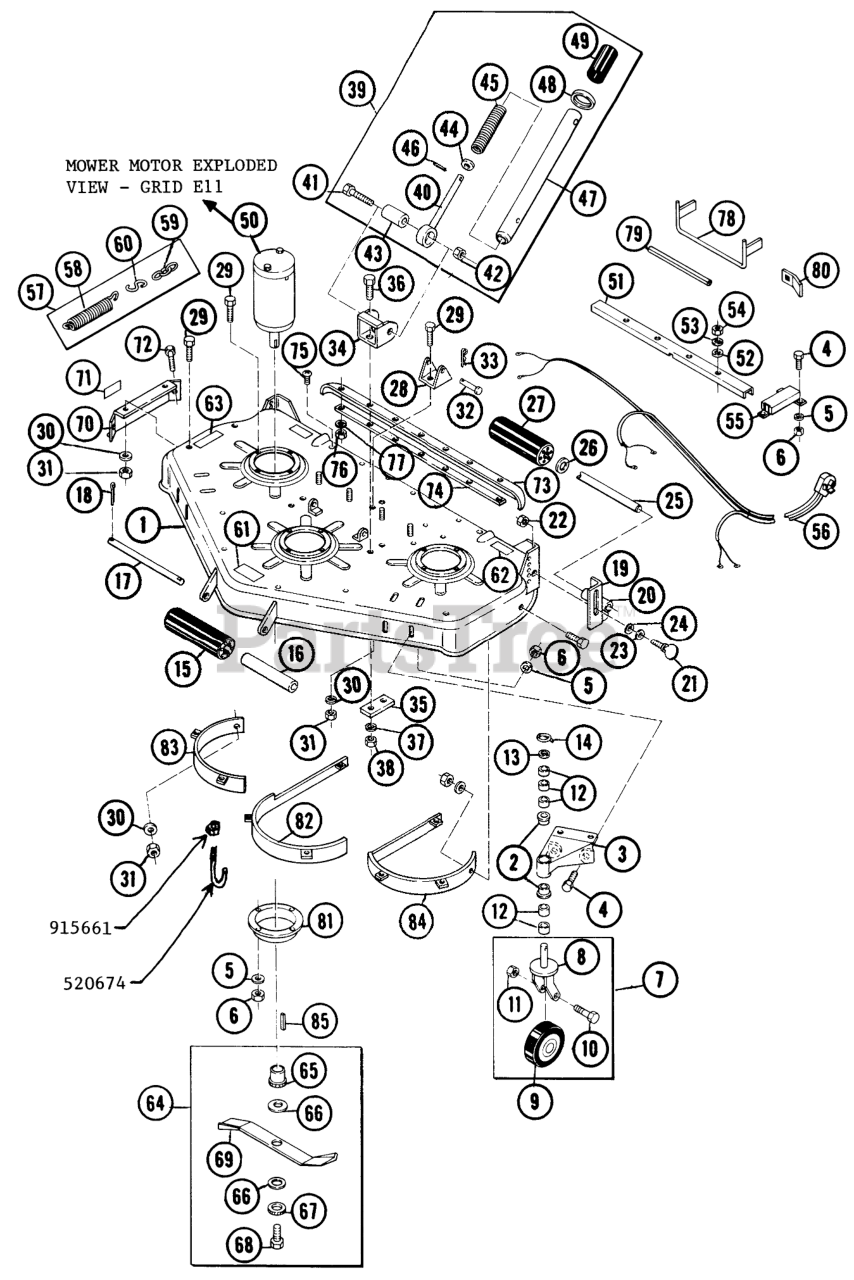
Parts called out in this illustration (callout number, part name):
1	Mower Deck
2	Bearing
3	Caster Support
4	Screw, 5/16-18 x 3/4
5	Lockwasher-5/16
6	Nut, Hex 5/16-18
7	Caster Assembly
8	Caster Yoke
9	Caster Wheel
10	Bolt, Hex 1/2-13 x 3 1/8
11	Locknut-1/2-13
12	Spacer
13	Washer-3/4
14	Spring Pin
15	Front Roller
16	Tubing
17	Shaft
18	Cotter Pin 1/8 x 1
19	Right Rear Roller Adjuster
20	Left Rear Roller Adjuster
21	Thumb Screw-3/8-16
22	Locknut-3/8-16
23	Lockwasher 3/8
24	Washer-3/8
25	Rear Roller Shaft
26	Washer
27	Rear Rubber Roller
28	Lift Clevis
29	Bolt, 1/4-20 x 5/8
30	Lockwasher 1/4
31	Nut, 1/4-20
32	Clevis Pin
33	Hairpin Cotter
34	Mower Arm Mounting Bracket
35	Reinforcement Plate
36	Bolt, Hex-3/8-16 x 1
37	Lockwasher 3/8
38	Nut, Hex 3/8-16
39	Mower Arm Assembly
40	Lower Mower Arm Rod
41	Bolt, Hex-5/8-11 x 3"
42	E.S. Nut 5/8-11
43	Rubber Bushing
44	Washer, 5/8 Plain
45	Spring
46	Roll Pin-1/8 x 15/16
47	Mower Arm Assembly
48	Retaining Ring
49	Mower Wear Sleeve
50	Mower Motor
51	Wire Cover
52	Washer-#8
53	Lockwasher-#8
54	Nut Hex-#8-32
55	Wire Box
56	Wire Harness
57	Helper Spring Assembly
58	Helper Spring
59	Chain
60	"S" Hook
61	Caution Decal
62	Caution Decal
63	Height Adjustment Decal
64	Blade Clutch Assembly
65	Clutch Body
66	Fiber Washer
67	Clutch Washer
68	Self Locking Cap Screw-5/16-24 x 1 1/2
69	BLADE KIT (AP25)
70	Side Cover-w/Decal
71	Caution Decal
72	Nut 1/4-20
73	Rear Mower Flap
74	Rear Mower Strip
75	Screw, Phillips Pan HD. #10-32 x 7/16
76	Nut #10-32
77	Lockwasher #10
78	Front Mower Guide
79	Sleeve
80	Clamp-Angle
81	Shell Collar
82	Center Baffle
83	Right Side Baffle
84	Left Side Baffle
85	Key, Woodruff
